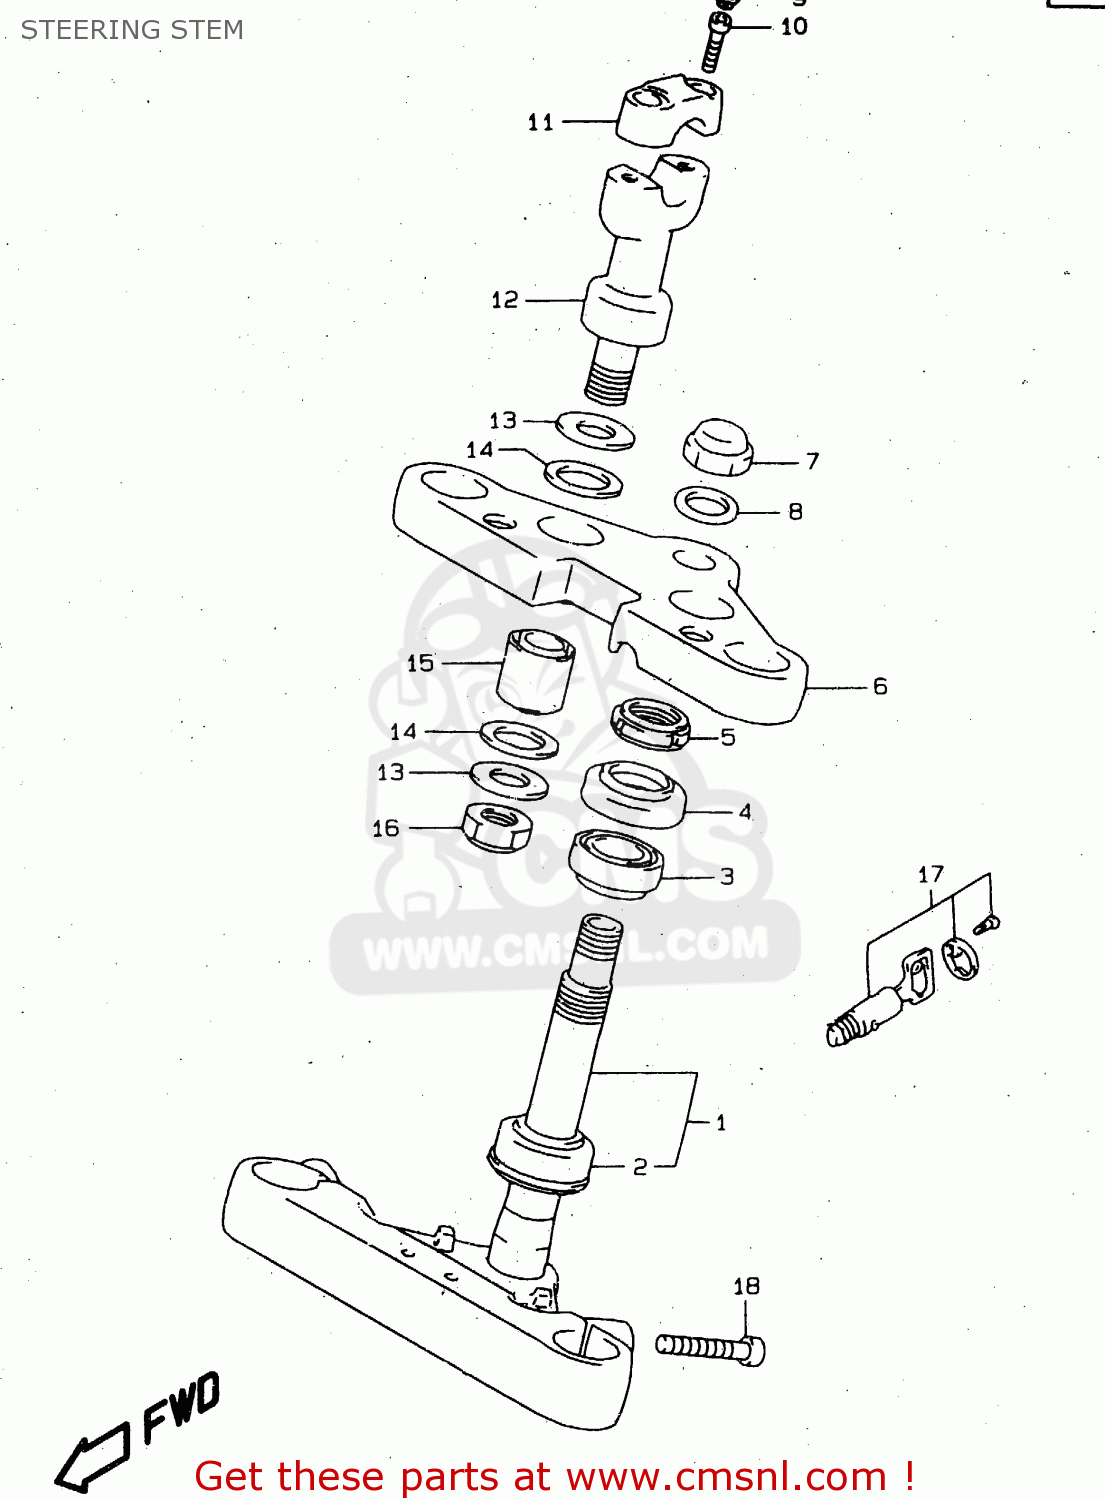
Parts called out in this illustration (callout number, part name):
1	STEM,STEERING
2	BEARING(30X55X17)
3	BEARING(25X47X15)
4	SEAL,STEERING UPR DUST
5	NUT,STEERING STEM(25X44X10)
6	HEAD,STEERING STEM
7	NUT,CAP
8	WASHER(22.5X32X1.6)
9	CAP(OD:14.5)
10	BOLT
11	HOLDER,HANDLE UPR
12	HOLDER,HANDLE
13	WASHER
14	SEAT,RUBBER
15	CUSHION
16	NUT
17	LOCK SET,STEERING
18	BOLT
